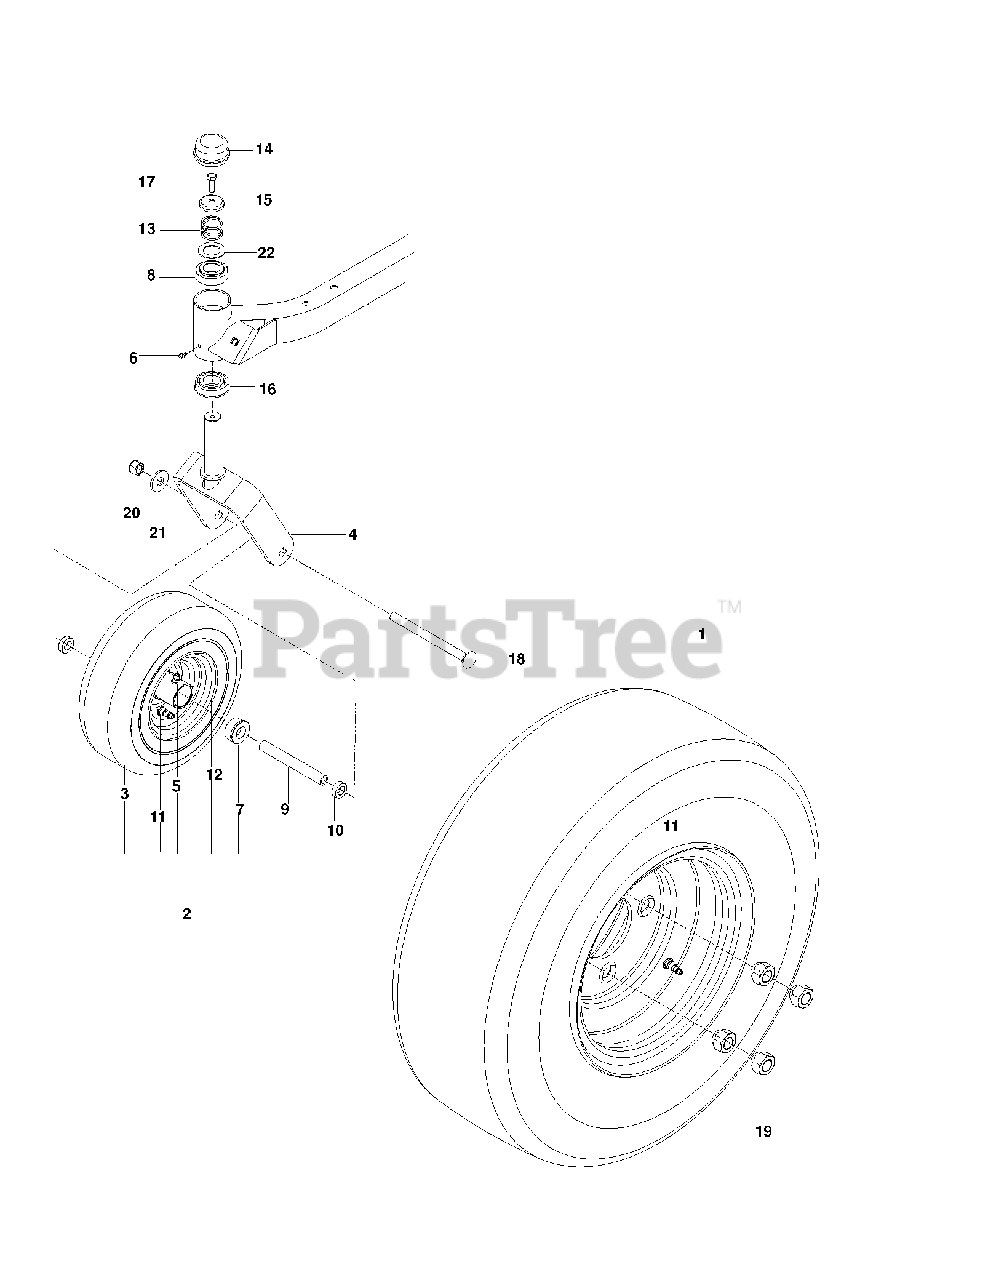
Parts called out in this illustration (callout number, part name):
1	REAR WHEEL AND TIRE
2	TIRE, CASTER, COMPLETE
3	TIRE, 4. 10-5.4 PLY
4	CASTER DK BLUE
5	ZERK
6	ZERK, 3/16, DRIVE IN
7	BUSHING, WHEEL, 3/4"
8	BUSHING, CASTER
10	SPACER, 5/16"
11	VALVE STEM TR-412
13	SPRING, CASTER
14	GREASE CAP
15	CASTER.PLUG
16	BEARING FLANGED
17	5/16-18X1 HHB G5W/NY
18	RHSNB 1/2-13 X 6.50 GR2 ZD
19	LUG NUT 1/2F
20	NUT 1/2-13 HEX CNTRLK GR 5 ZD
21	WASHER, 1.025 ID X 1.64
22	WASH USS FLAT 1/2
